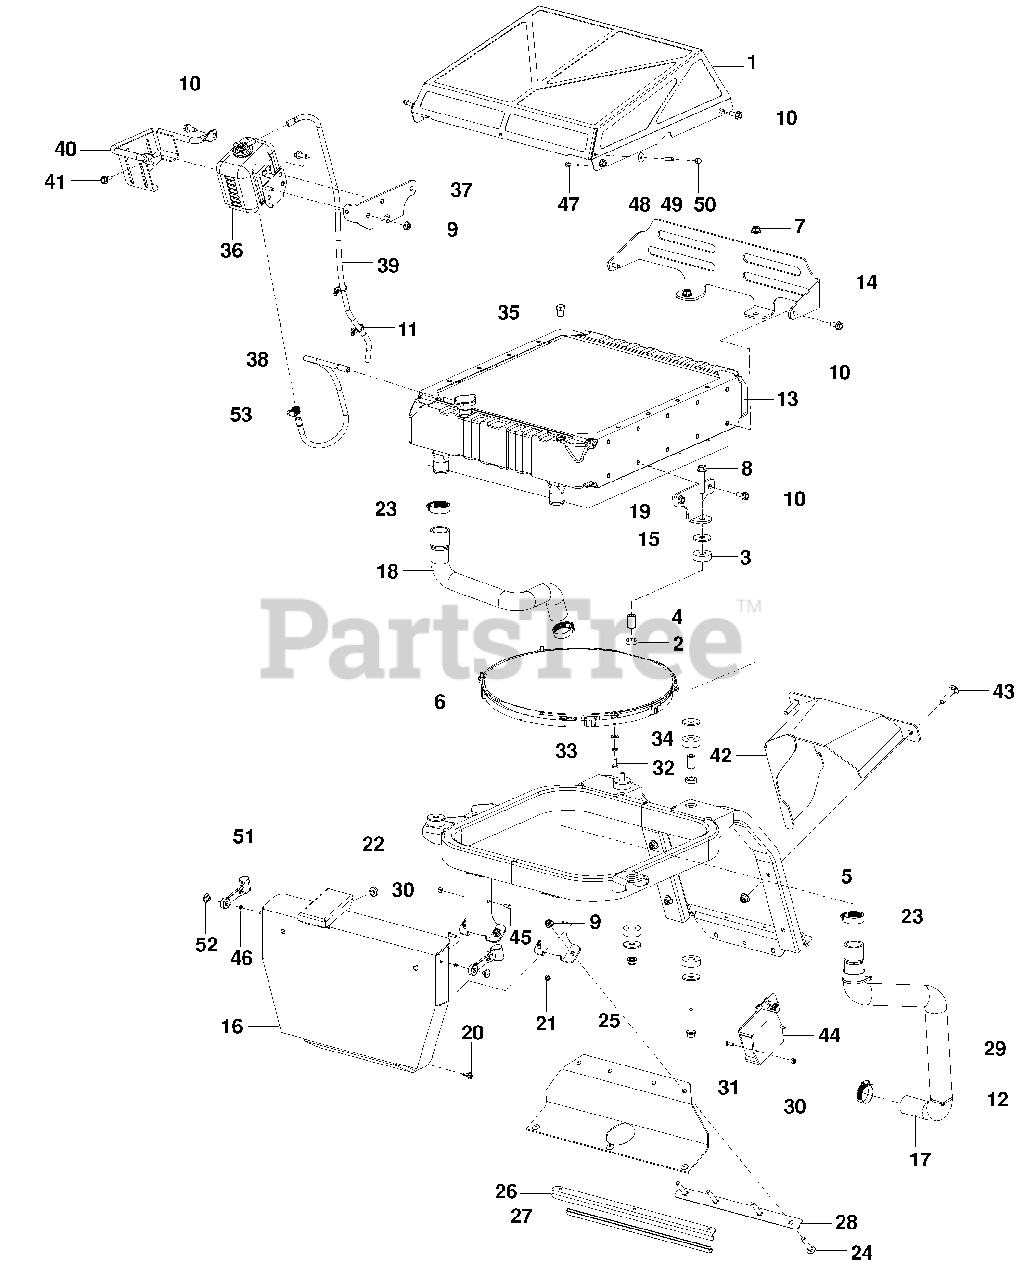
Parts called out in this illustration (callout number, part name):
1	Screen, Debris, Blk
2	Iso-Mount Insert
3	Iso-Mount Bushing
4	Iso-Mount Bushing
5	Mount, Radiator, Gry
6	Fan, Electric
7	Nut 3/8-16 Hex Flg Nyloc
8	Hhfs 3/8-16 X 2
9	Nut 5/16-18 Hex Flange Nyloc
10	Hhfs 5/16-18 X 3/4
11	Tie Wrap W/ Clip
14	Mount, Radiator Rr Blk
15	Washer 7/16 Flat
16	Guard, Hose Blk W/ Decal
17	Hose, Radiator, Lt
18	Hose, Radiator, Rt
19	Mount, Radiator, Ft Blk
20	Screw 1/4 -20 X 5/8 Thdroll
21	Nut 1/4-20 Hex Thin Nyloc
22	Grommet, Bumper
23	Clamp, Hose
24	Rhsnb 5/16-18 X 1 3/4
25	Guard, Belt
26	Strap, Belt Guard Blk
27	Flex Trim Blk
28	Strap, Guard
29	Sleeve, Hose
30	Nut #10-24 Hex Nyloc
31	Screw#10-24 X .625 Mach
32	Hcs 1/4-20 X 5/8
33	Washer 1/4 Splt Lk
34	Washer 1/4 Flat Sae
35	Fitting, Pipe, 1/4 Npt
36	SCREW 3/8-16 x 1 1/2 HEX HD
37	Mount, Radiator, Rt
38	Hose, Overflow Upper
39	Hose, Overflow Lower
40	Guard, Overflow Blk
41	Bolt 5/16-18 X 3/4 Thd Frm
42	Shield, Belt, Gry W/ Decal
43	Rhsnb 3/8-16 X 1 3/4
44	Module, Fan Reverse
45	Screw #10-24 X 1/2 Slt Hex Hd
46	Washer 3/16 Lock
47	Screw #10- 24 X 11/8
48	Washer 3316 X 3/4 X 16 Ga
49	Spacer, Split
50	Nut, Acorn #10-24
51	Latch, Hood
52	Plated, Weld Nut
